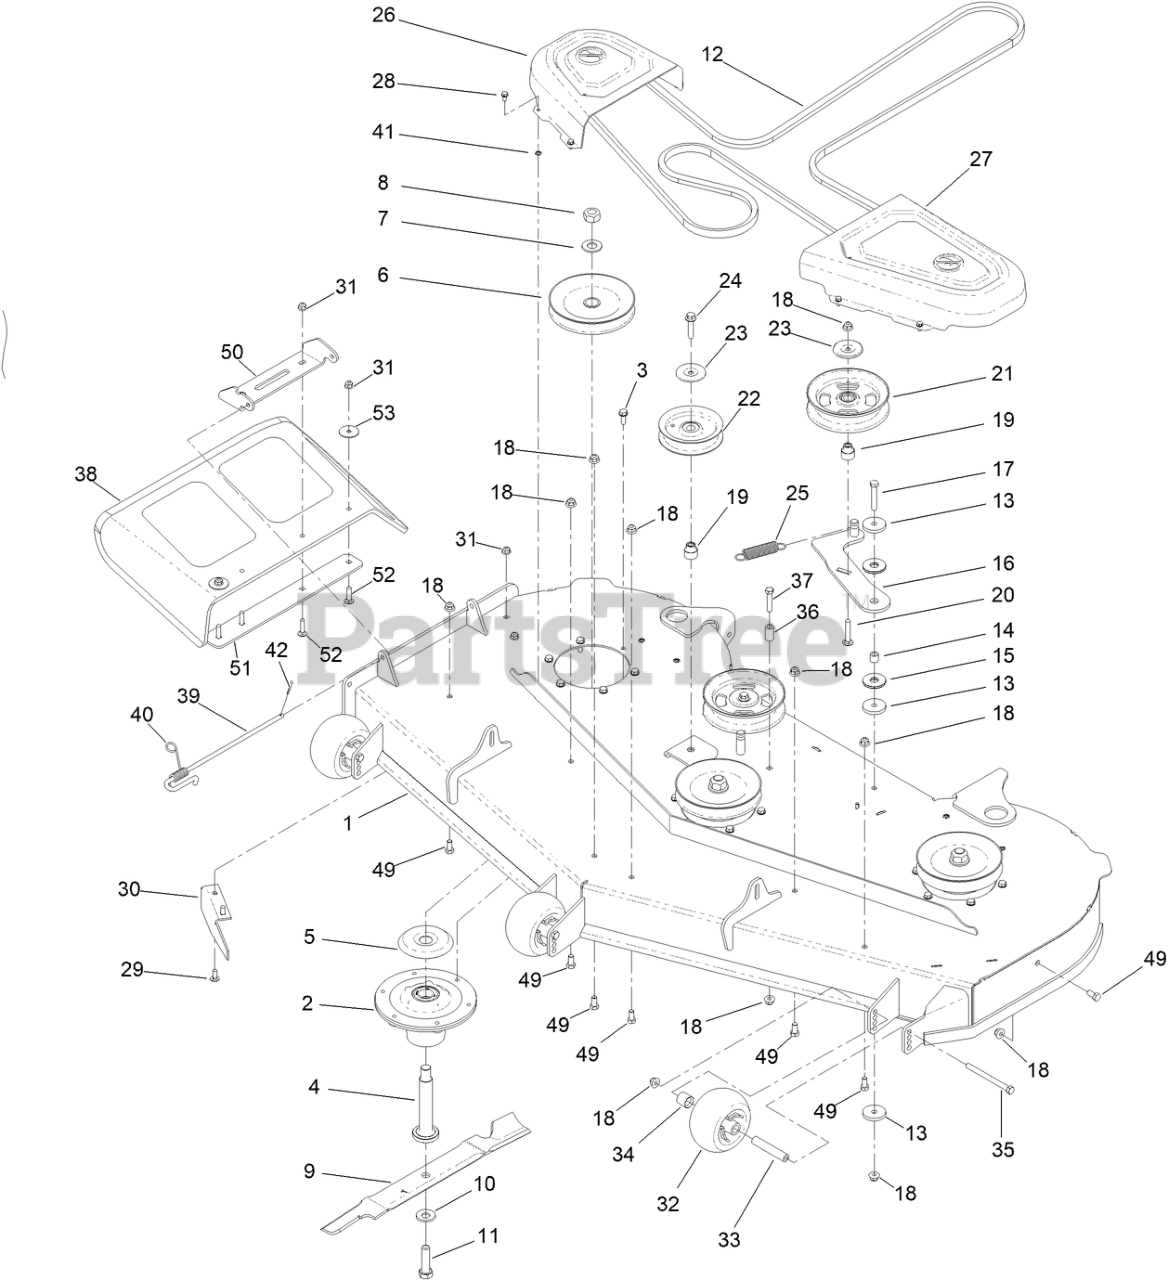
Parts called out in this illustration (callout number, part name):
1	DECK ASM-60"
2	SPINDLE ASM
3	SCREW-TAPTITE
4	SHAFT-SPINDLE
5	SHIELD-BEARING
6	PULLEY
7	WASHER
8	NUT-HEX
9	BLADE - HIGH FLOW, 20.50 IN.
10	WASHER-BELLEVILLE
11	SCREW-BLADE
12	BELT-V
13	WASHER-PLAIN
14	BUSHING-IDLER
15	WASHER-FRICTION, COMPOSITE
16	IDLER ARM ASM
17	SCREW-HH
18	NUT-HF, NI
19	BUSHING-IDLER
20	SCREW-CARR
21	PULLEY-IDLER, FLAT
22	PULLEY-IDLER, FLAT
23	SHIELD-DUST
24	SCREW-HHF
25	SPRING-EXTENSION
26	COVER-BELT, RH
27	COVER-BELT, LH
28	SCREW-HWH
29	SCREW-CARR
30	BAFFLE-CUTOFF
31	NUT-HF, NI
32	ROLLER-SCALP, ANTI
33	TUBE-SPANNER
34	SPACER-AXLE, REAR
35	SCREW-HH
36	SPACER-FENDER
37	SCREW-HH
38	DEFLECTOR
39	PIN-CHUTE
40	SPRING-TORSION
41	NUT-RETAINING
42	PIN-COTTER
49	SCREW-HH
50	BRACKET UPPER, DEFLECTOR
51	PLATE-DEFLECTOR
52	SCREW-CARR
53	WASHER-FLAT
